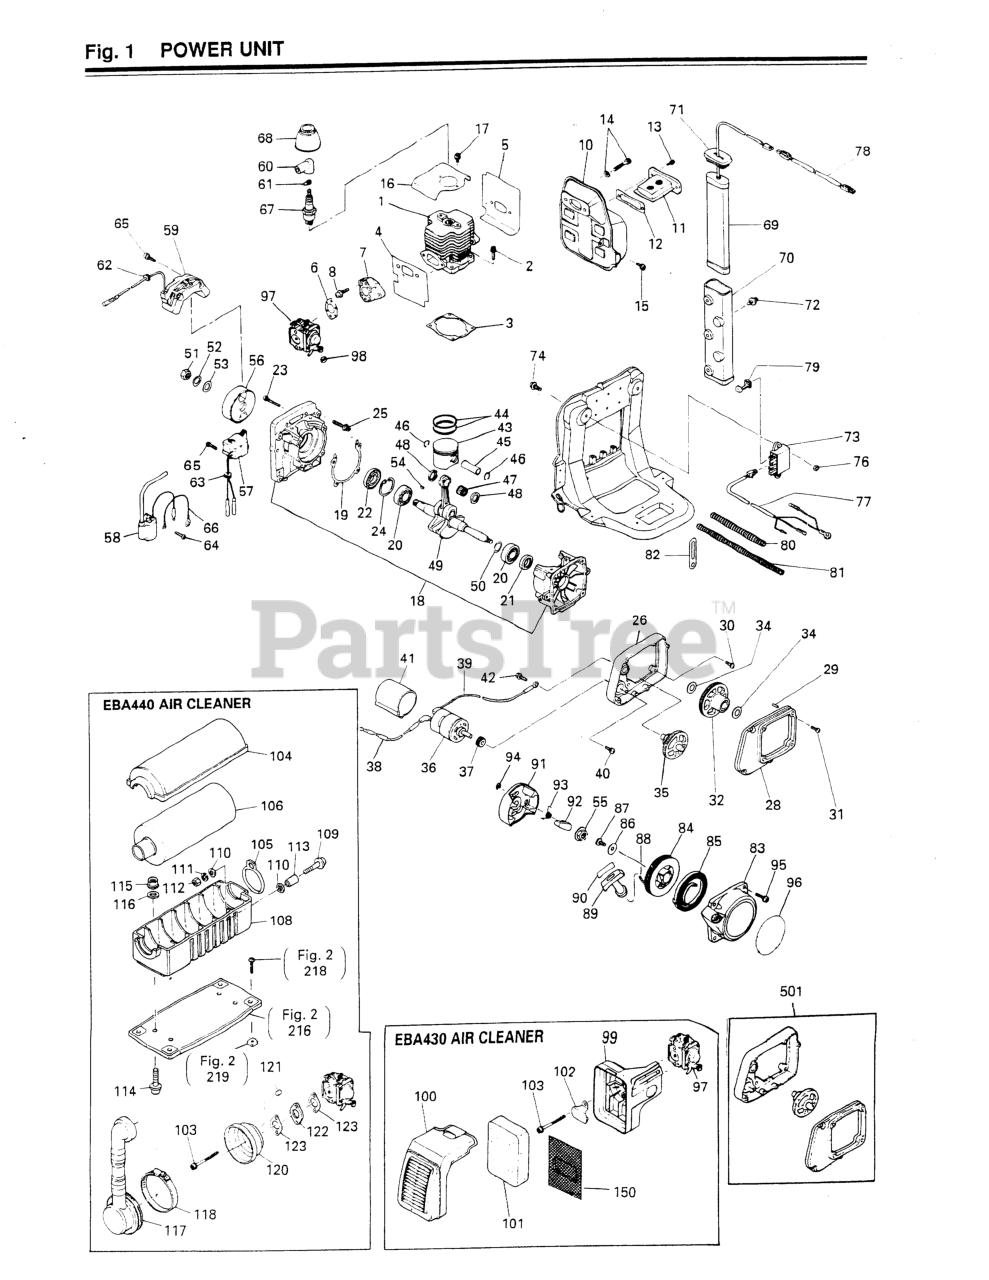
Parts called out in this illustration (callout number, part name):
8	BOLT, M5 X 25 (RPLS.1491-14120
11	ARRESTER
13	SCREW, M4 x 10
15	SCREW, M5 x 12
17	SCREW, M5 x 12
18	CRANKCASE
21	SEAL, OIL - STARTER SIDE
23	SCREW, M5 x 30(RPLS 0263-00530
24	RING, SNAP, M35 X 1.5
26	CASE COMPLETE
29	PIN, DOWEL
31	SCREW, M4 X 16
35	GEAR (B) (RPLS-23201)
36	MOTOR
37	GEAR (RPLS -24150)
38	CORD (YELLOW)
39	CORD (BLACK)
40	SCREW, M4 x 10
41	COVER, MOTOR
42	BOLT, M5 X 12
44	RING, PISTON (RPLS -41210)
45	PIN, PISTON
46	RING, SNAP
47	BEARING
48	WASHER (RPLS 1491-41510)
50	SHIM (REPLACES 848-870-G000)
52	WASHER, M10 X 25
53	WASHER, M10 x 1.6
54	KEY
58	COIL, IGNITION
61	SPRING
63	GROMMET
64	SCREW, M4 x 16
65	SCREW (REPLACES -30414)
66	CABLE COMPLETE
68	CAP (NO LONGER AVAILABLE)
69	BATTERY
72	CLIP
73	RELAY
74	BOLT
76	NUT, M5 X 4
77	CORD ASSEMBLY
78	CORD ASSEMBLY
83	RECOIL ASSEMBLY
84	REEL
85	SPRING, SPIRAL
89	KNOB
91	PULLEY ASSEMBLY
92	RATCHET
93	SPRING, RETURN
94	E-RING
95	SCREW (USE 0263-90520 )
96	LABEL, RECOIL
98	CAP, CABLE END
103	SCREW, M5 X 55
104	COVER, CLEANER
105	BAND
106	ELEMENT
108	CASE, CLEANER
110	WASHER, M5 X .8
111	WASHER, SPRING M4 x 1.3
112	NUT, M5 X 4
113	COLLAR (NLA)
114	SCREW, M5 x 16
115	NUT (B)
116	WASHER, M5 X .8
118	CLAMP
120	CASE, CLEANER
121	PLUG (NO LONGER AVAILABLE)
501	KIT, GEAR
NI	CLEANER, AIR
